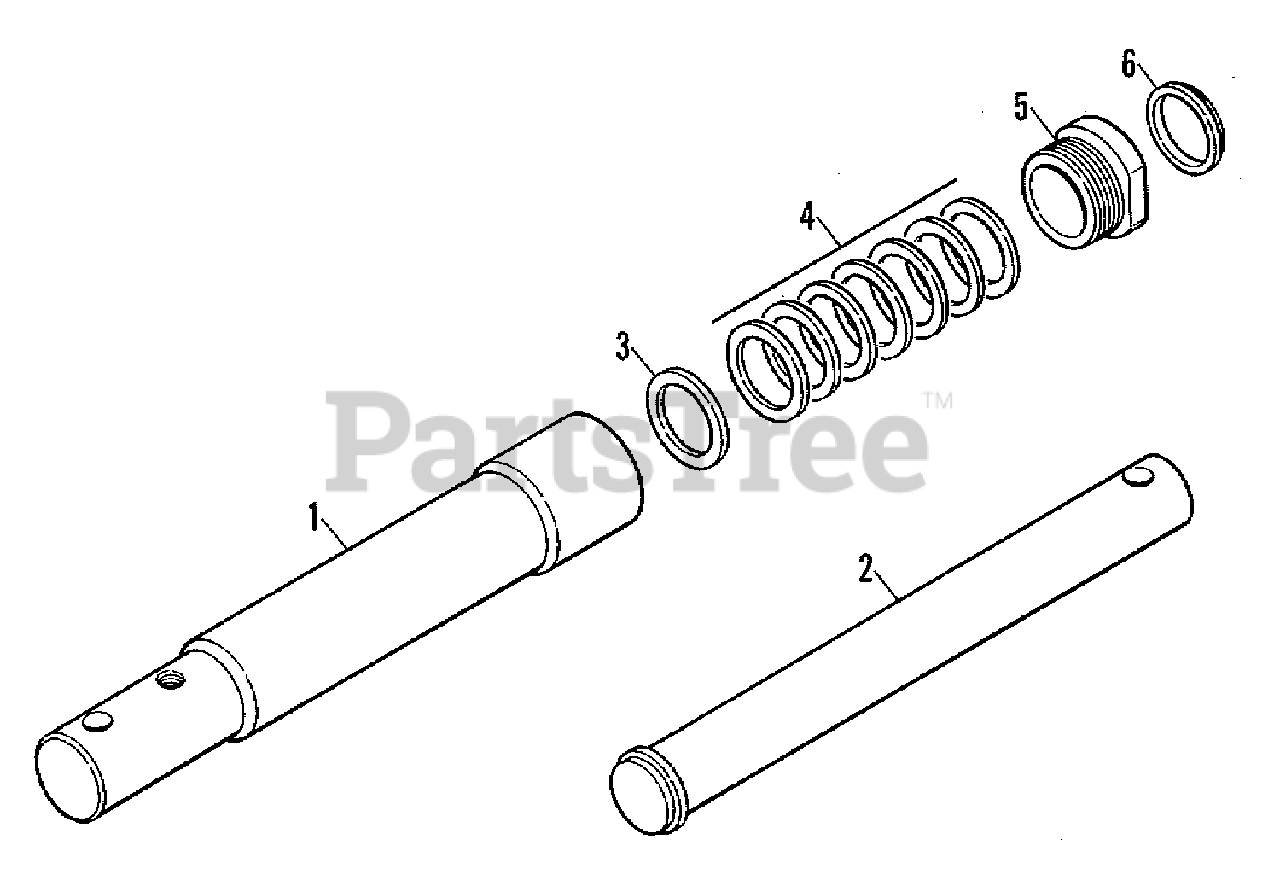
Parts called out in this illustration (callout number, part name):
1	TUBE ASSEMBLY
3	EXPANDER, Ring
4	PACKING SET, Vee
5	NUT, Packing Gland
6	WIPER, Neoprene
